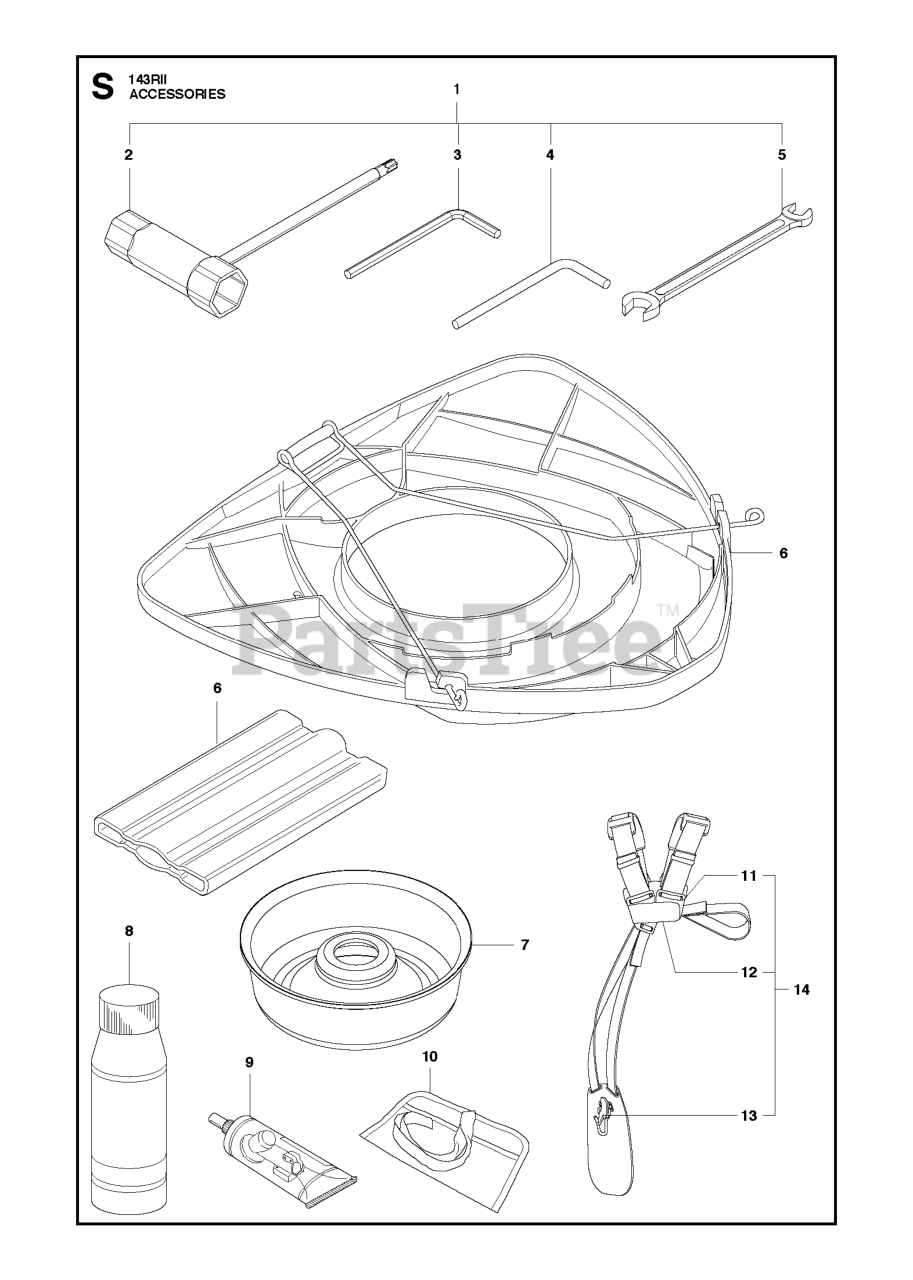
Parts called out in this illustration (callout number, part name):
5	WRENCH SPANNER
6	TRANSPORT GUARD
6	BAR GUARD
7	SUPPORT CUP
8	Air Filter Oil 1l.
9	BEVEL GEAR GREASE
13	HOOK, CPL.
14	HARNESS DUO
